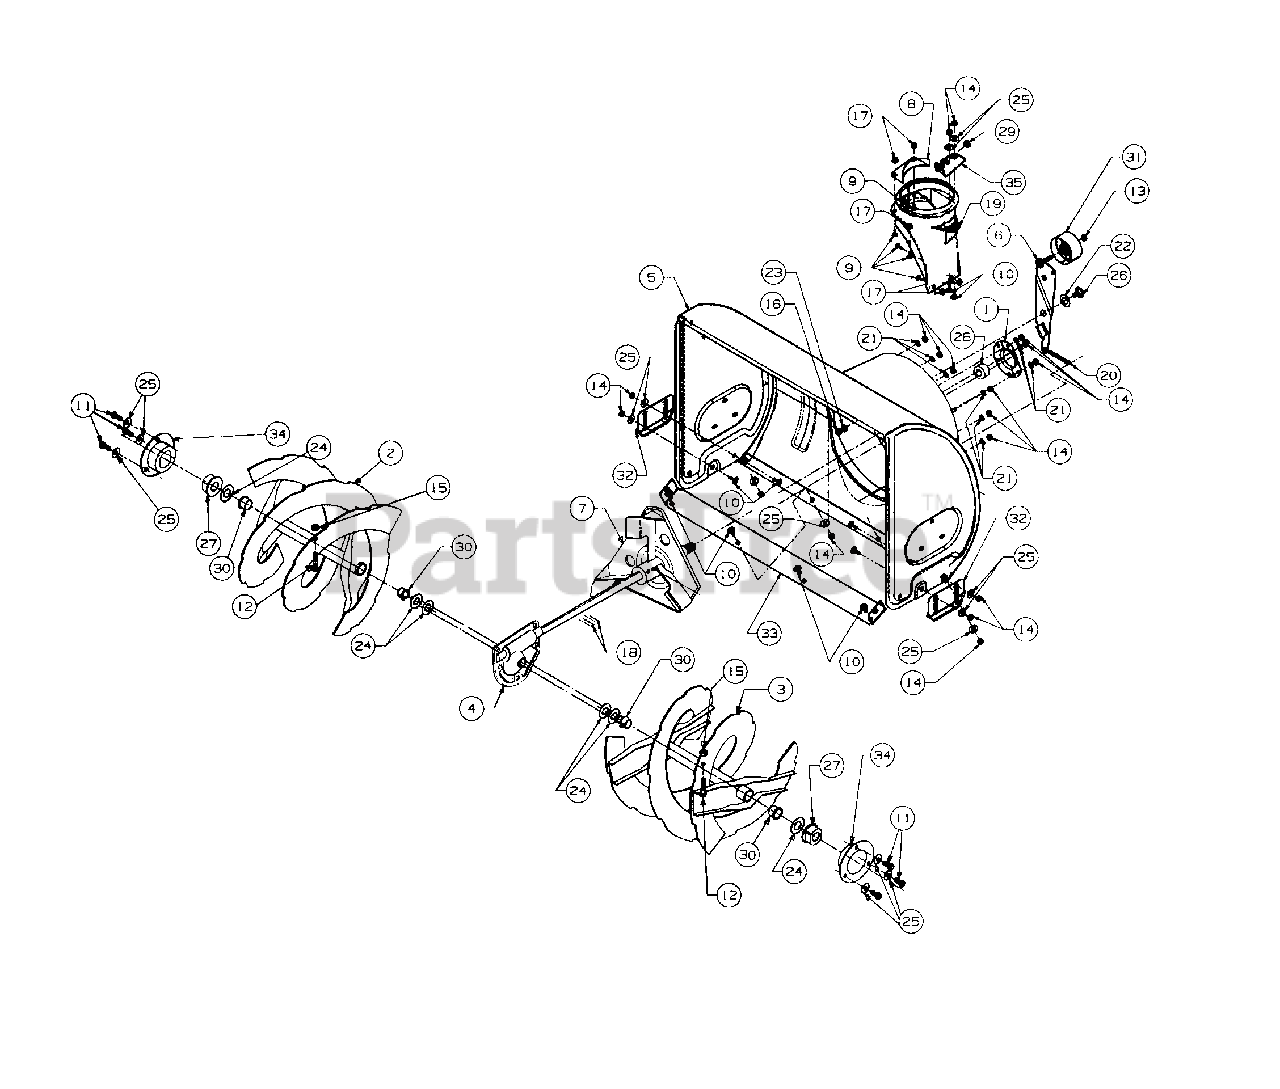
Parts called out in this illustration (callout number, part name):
1	Housing-Bearing
9	Screw-Carriage
10	Screw-Carriage
11	Screw-Hex
12	Shear Bolt
13	Nut-Hex Lock
14	Nut-Hex
15	Nut-Hex
16	Nut-Hex
17	Nut-Hex Lock
18	Pin-Spring
19	Adapter-Chute
20	Spring
21	Washer-Lock
22	Washer-Flat
23	Washer-Lock
24	Washer-Flat
25	Washer-Bell
26	Screw-Shoulder
27	Bearing-Flange
28	Bearing-Ball
29	Bushing-Plastic
30	Bushing-Flange
31	Idler-Flat
